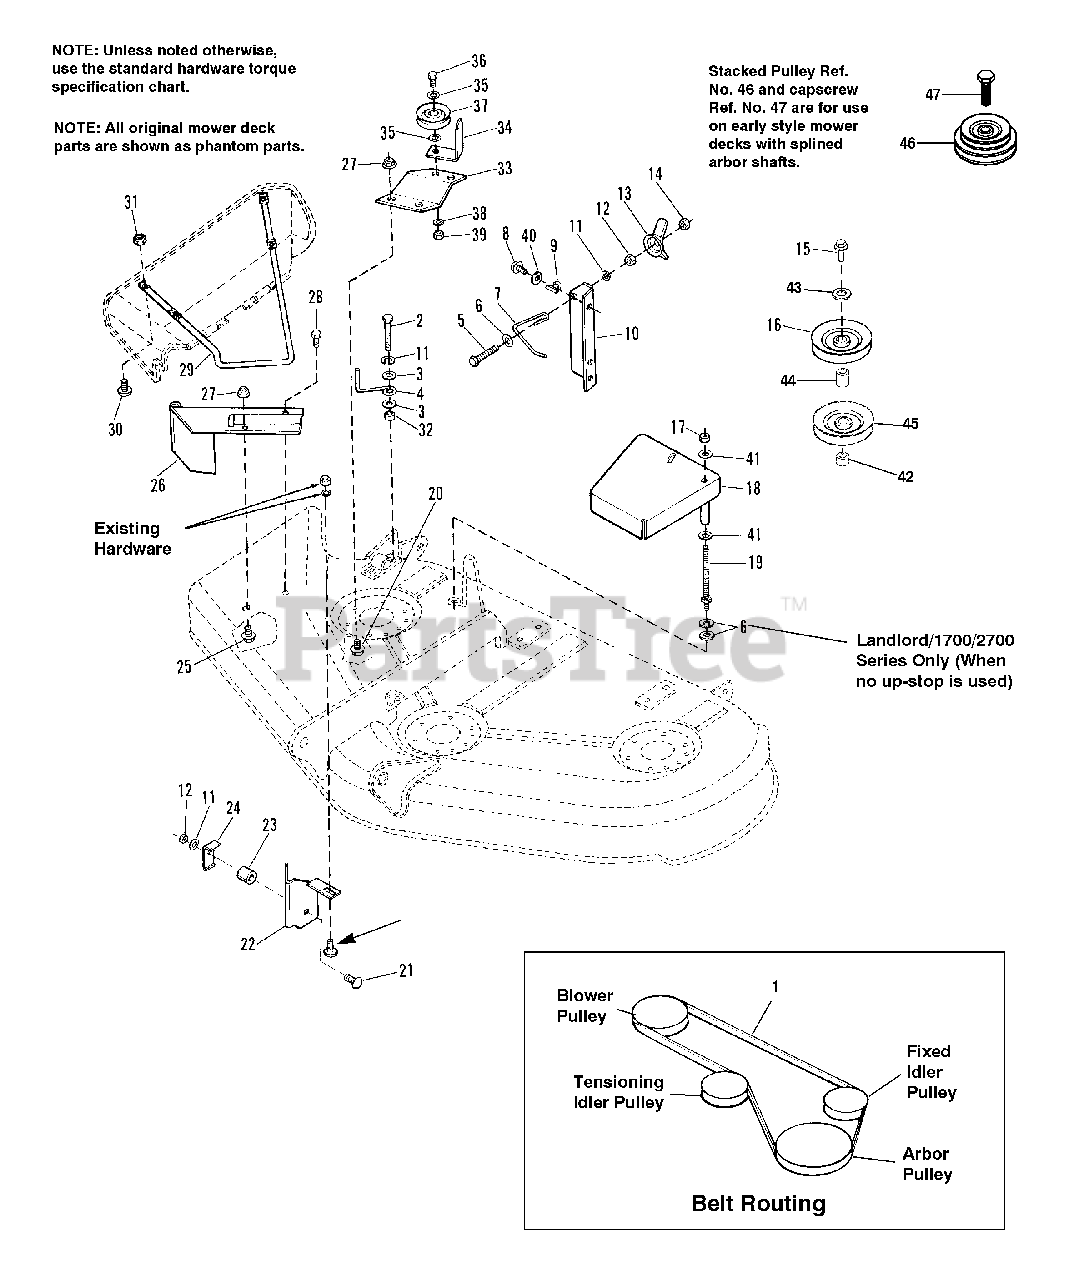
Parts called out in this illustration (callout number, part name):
2	CAPSCREW 5/16-18 x 1-1/2
3	WASHER, Flat
5	CAPSCREW 5/16-18 x 2-1/2
6	WASHER, Flat
7	SPRING LATCH
8	SCREW, Taptite 1/4-20 x 1/2
10	ANCHOR, Turbo, 44"
11	LOCKWASHER 5/16
12	NUT, Hex, 5/16-18
13	NUT, Wing Assy, 5/16
14	NUT, Hex, Centerlock 5/16-18
15	NUT, Sleeve
16	PULLEY ASSY Turbo
17	HEX NUT, Nylock
18	SHIELD ASSY., Belt
19	STUD, 5/16-18 x 5-13/64
20	CAPSCREW, Hex Hd. 5/16-18 x 7/8
21	CARRIAGE BOLT 5/16-18 x 1-1/4
22	BRACKET ASSY., Cutoff
24	BRACKET, "L"
25	CARRIAGE BOLT, 5/16-18 x 3/4
26	PIVOT ASSY., 44
27	NUT, Hex, Flange
28	SCREW. Hex Whiz- lock 5/16-18 x 2
29	ROD, Deflector
30	SCREW, Truss Hd
31	NUT, Nylock, #10-24
33	BRACKET, Idler, Turbo
34	LATCH, Belt Cover
35	WASHER, Flat
36	CAPSCREW, 3/8-16 x 1-1/2
37	PULLEY ASSY, Idler
38	LOCKWASHER, 3/8
39	NUT, Hex, 3/8-16
40	WASHER, Flat, 1/4
41	WASHER, Flat
42	HUB (Existing)
43	WASHER, Belleville
44	HUB, Pulley, Double, 1.160" Long
45	V-PULLEY (Existing)
46	PULLEY, Double
47	CAPSCREW, 7/16-14 x 2
